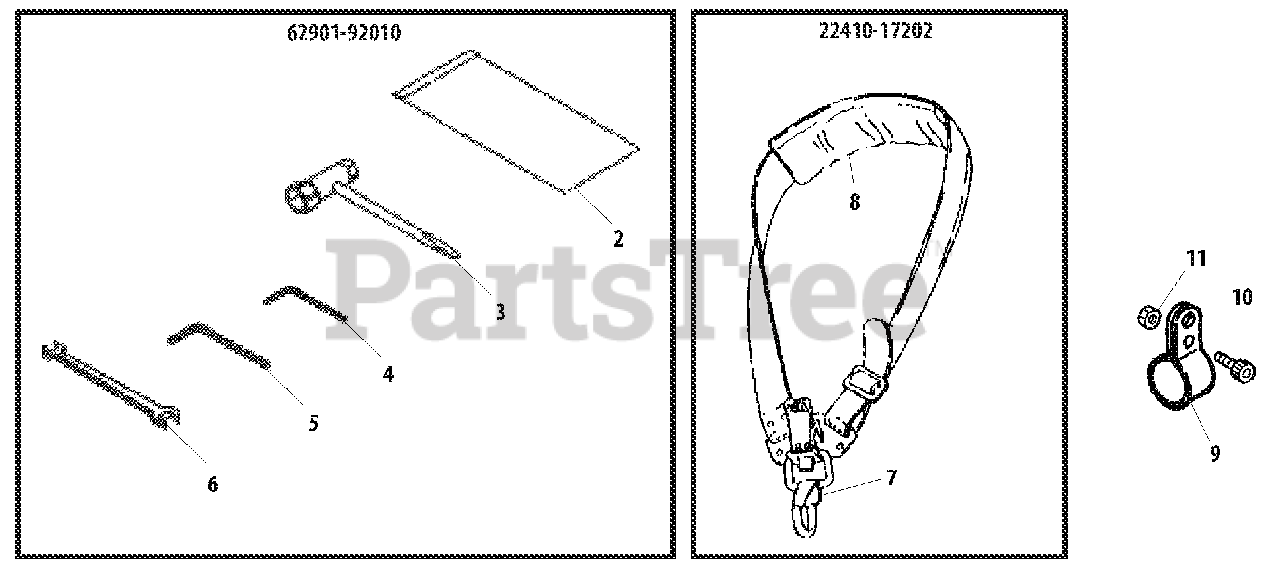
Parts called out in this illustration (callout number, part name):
2	BAG, TOOL
3	T-WRENCH 16×13
4	WRENCH, ALLEN 3 MM
5	WRENCH, ALLEN 4 MM
6	SPANNER 8×10
7	HOOK, SNAP
8	PAD, SHOULDER
9	HANGER
10	BOLT 5×12
11	NUT M5
22410-17202	HARNESS ASSY
62901-92010	TOOL KIT, SERVICE
